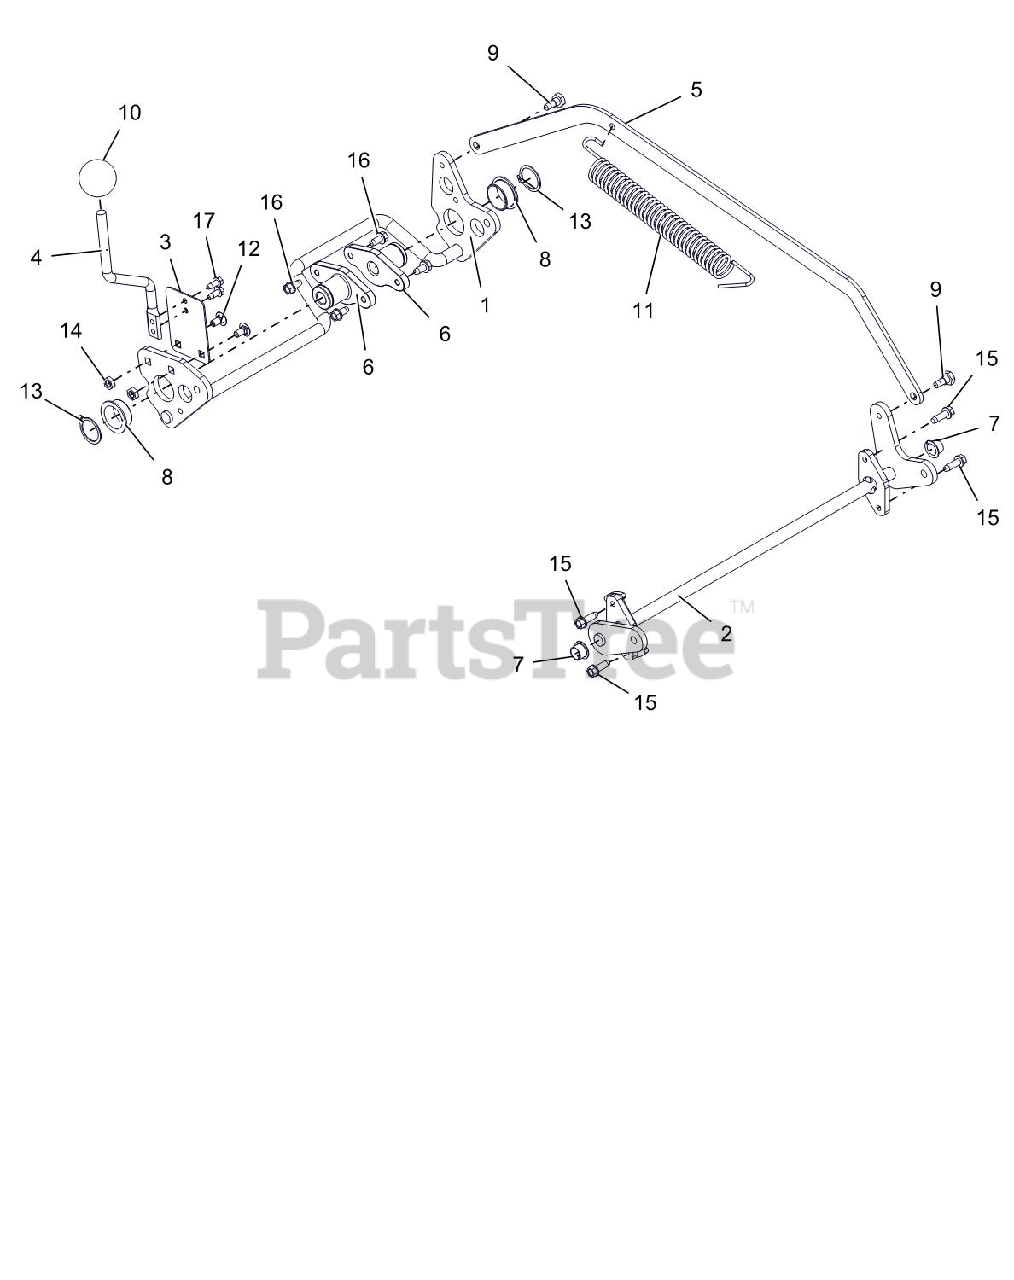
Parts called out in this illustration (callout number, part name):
1	WLDMT, REAR AXLE
2	WMT, LM FRONT AXLE
3	PLATE, HOC SPRING
4	LEVER, HOC ADJUSTMENT
5	LINKAGE, HOC CONNECT
6	HUB, LM REAR AXLE
7	BUSHING, POLYLINER-.50 SPLIT
8	BSHG-FLG 1.0X1.125X.50X1.375 R
9	BOLT, SHLDR .320X.210X.25-20
10	KNOB,BALL -BLACK 1.47" .375-16
11	SG-TENS .121X1.00X6.5 WLD
12	@BLT-RDHDSQNK .25-20X.50 G5YZ
13	RG-RTNG-EXT 1.00X.042
14	NUT-LK-CTR JAM .25-20 YWZC
15	SCR-TAP-PM .25-20X.75 TR YWZ
16	SCR-TAP .25-20X.50 HWH TR YWZ
17	@SCR-TAP 12-24X.50 HWH TR YWZC
